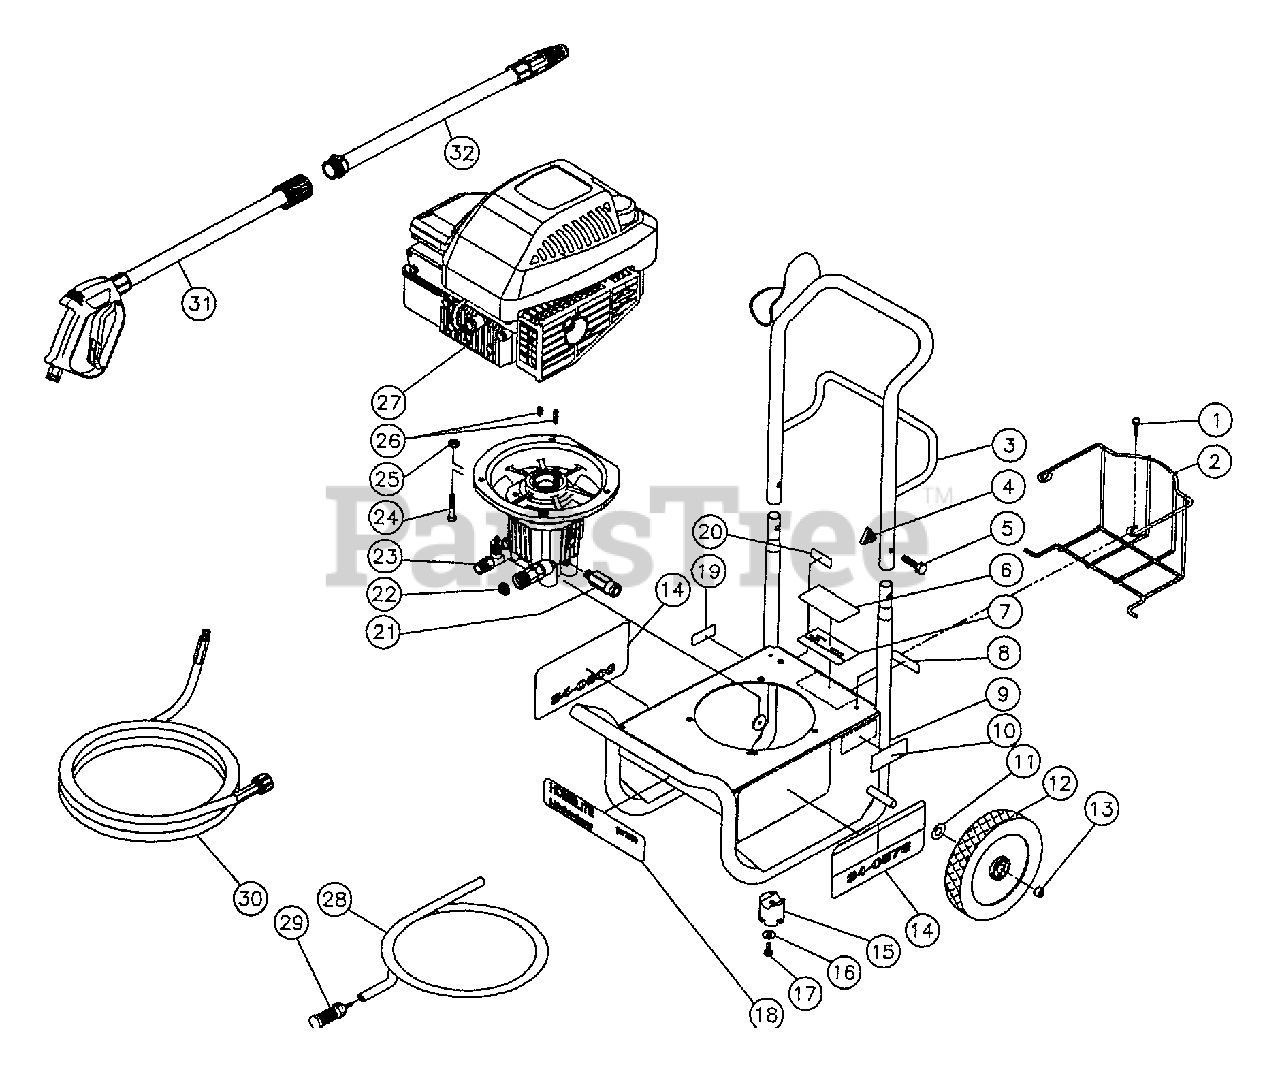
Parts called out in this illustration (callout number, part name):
6	Decal-Clear Laminate
7	Decal-Silver Sticker
8	Decal-Serial Number
10	Decal-Warning: Muffler Hot
14	Decal-Warn/Caution/Operate English
15	Isolator
18	Decal-1750 PSI
19	Decal-Caution: Allow to Cool
20	Decal-Adjustable Pressure
21	Heat Dump Valve
26	Key-Woodruff
27	Engine-4.0 HP B&S
28	Detergent Hose
29	Detergent Strainer
30	Pressure Hose
31	Gun w/Lance
32	Lance w/Nozzle (1.2 mm)
